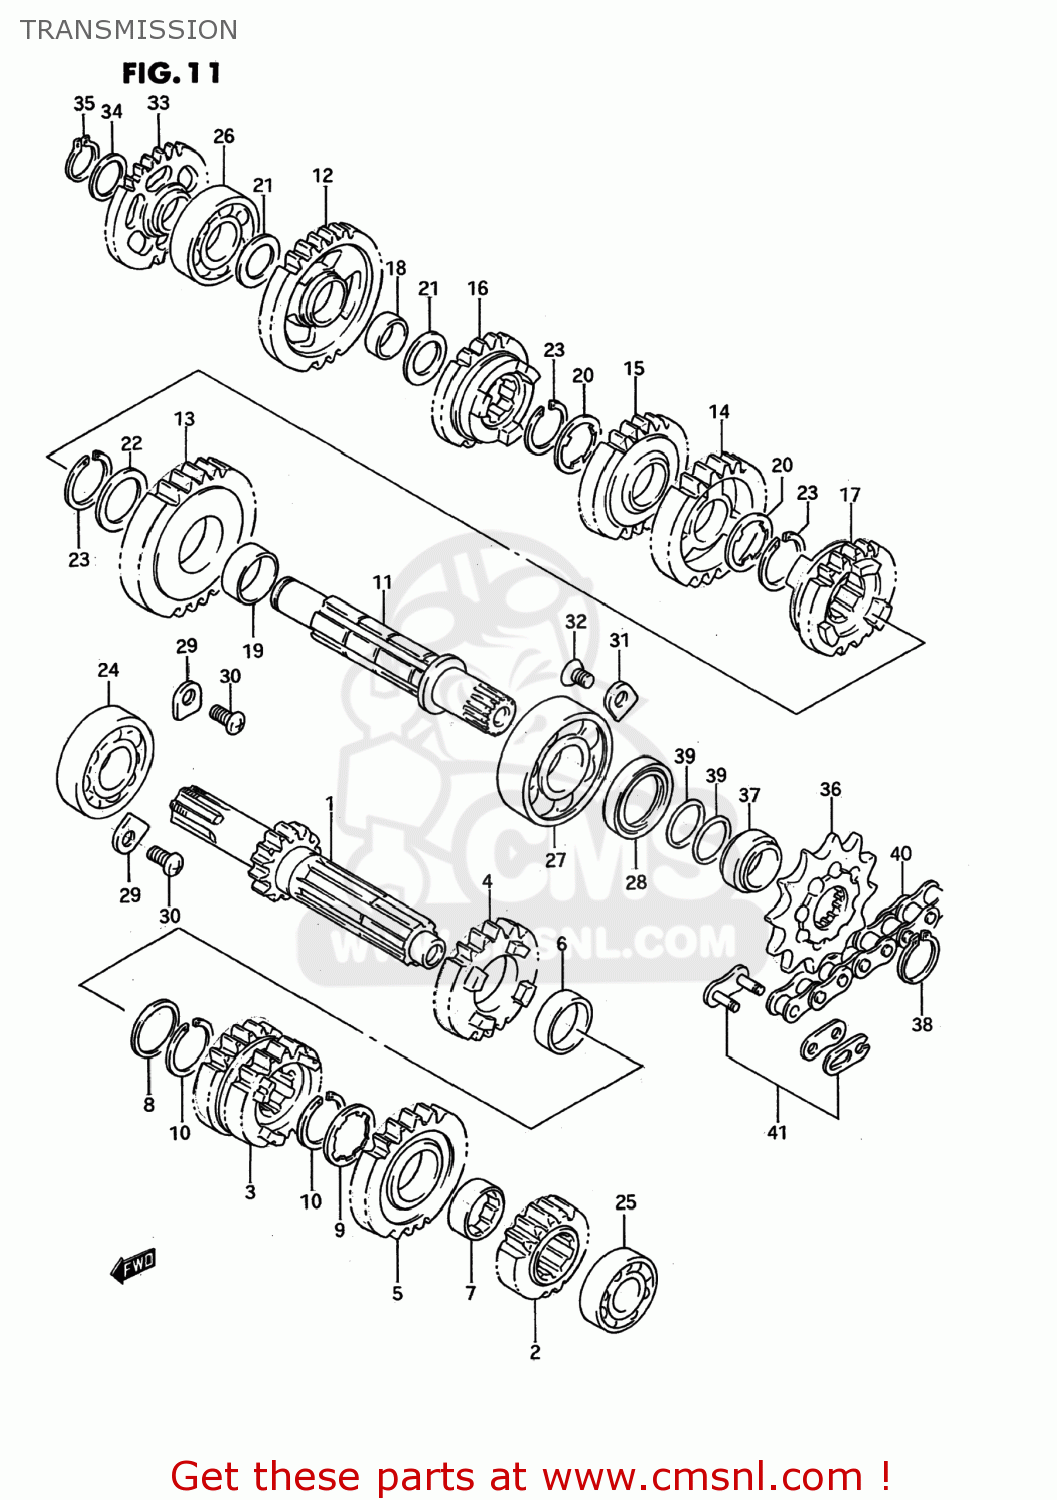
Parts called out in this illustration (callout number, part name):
1	SHAFT,COUNTER(NT:14)
2	GEAR,2ND DRIVE(NT:16)
3	GEAR,THIRD DRIVE
4	GEAR,FIFTH DRIVE (NT:19)
5	GEAR,SIXTH DRIVE (NT:20)
6	BUSHING
7	BUSH,6TH DRIVE GEAR
8	SHIM
9	WASHER,LOCK
10	CIRCLIP
11	SHAFT,DRIVE
12	GEAR,FIRST DRIVEN
13	GEAR,2ND DRIVEN(NT:28)
14	GEAR,THIRD DRIVEN
15	GEAR,FOURTH DRIVEN
16	GEAR,5TH DRIVEN(NT:20)
17	GEAR,SIXTH DRIVEN
18	BUSH(17X20X9)
19	BUSHING
20	WASHER
21	WASHER,THRUST
22	WASHER,THRUST
23	CIRCLIP
24	BEARING(20X47X12)
25	BEARING
26	BEARING(17X40X9.5)
27	BEARING(20X52X12.5)
28	SEAL,OIL(28X38X6)
29	RETAINER
30	SCREW
31	RETAINER,COUNTER BEARING,R
32	SCREW
33	GEAR,KICK STARTER IDLE
34	SHIM
35	CIRCLIP,17MM
36	SPROCKET,ENGINE
37	SPACER,ENGINE SPROCKET
38	CIRCLIP
39	O RING(D:1.9,ID:19.8)
40	CHAIN ASSEMBLY DID520DM.11
41	JOINT SET,CHAIN
